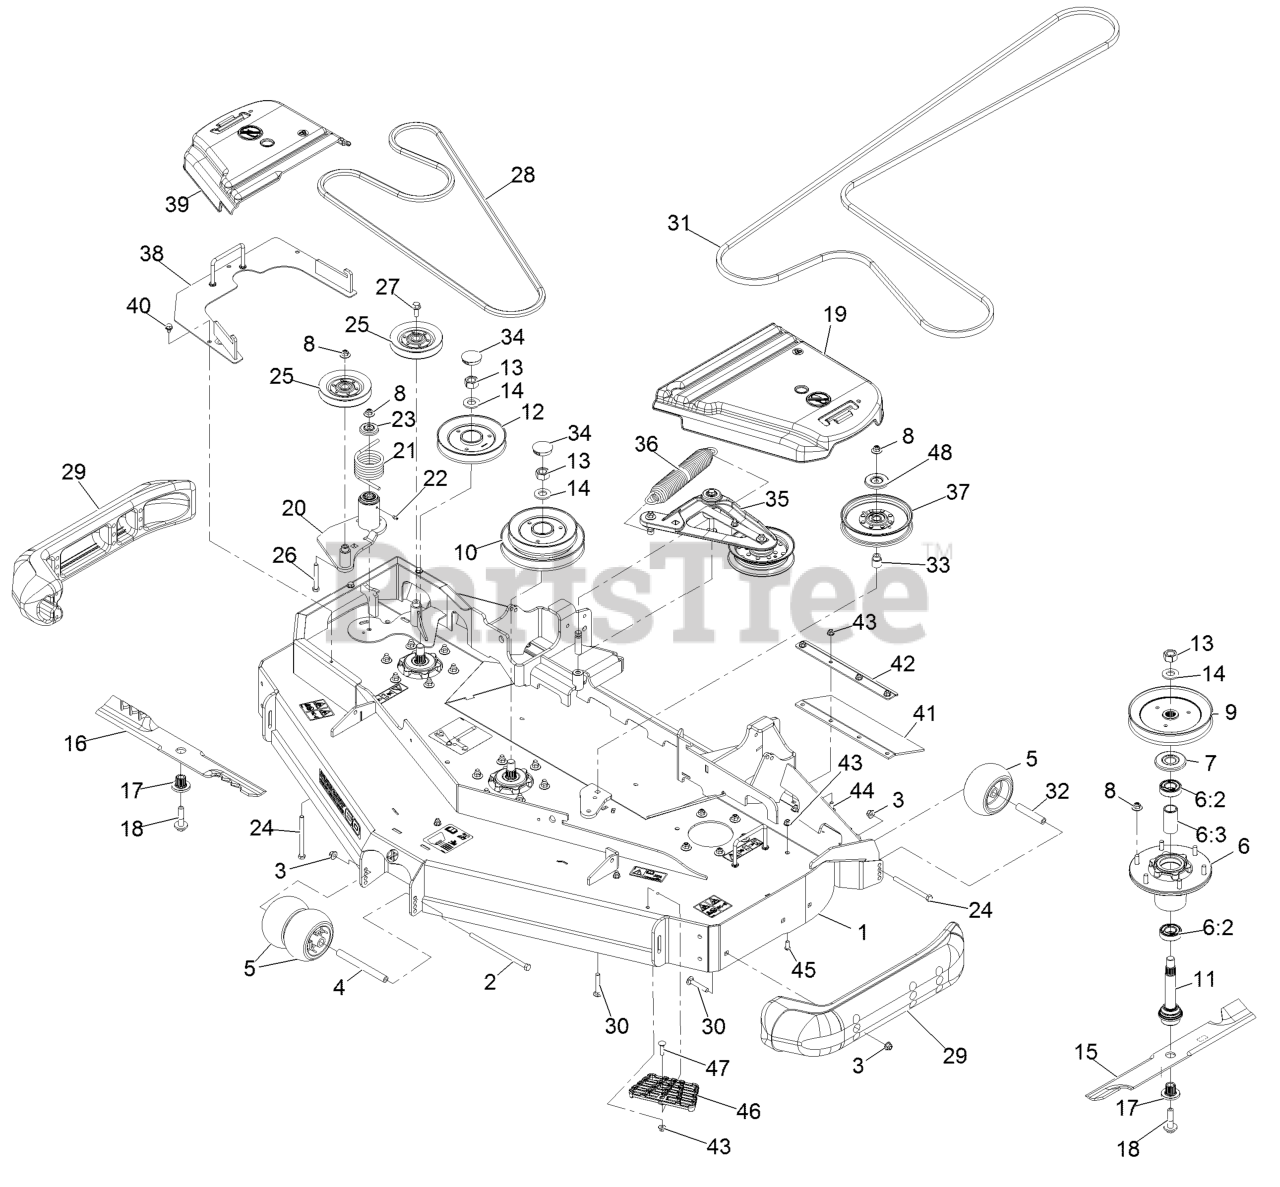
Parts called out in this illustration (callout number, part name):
1	Deck-Rd60 Nlz, W/Decals
2	Screw-HH 3/8-16 X 7 3/8
3	Nut-Nyloc 3/8-16 Flg
4	Spacer-Wheel
5	Roller-Scalp, Anti
6	ASM-Cutter Hsg With Bearings
6:2	Bearing-Ball
6:3	Spacer-Bearing
7	Guard,Bearing Top .989
8	Nut-Nyloc 3/8-16 Flg
9	Sheave,Blade Drive 7.25
10	Sheave, Double 60Rd
11	ASM-Spindle And Seal
12	Sheave-Rd Rev Drive Series 4
13	Nut-Hex
14	Washer-Spring Disc 3/4
15	Blade, Low Lift
15	Blade, Notched
15	Blade-Extreme 2, 20.50"
16	Blade-Extreme 2-20.50, Rd60
16	Blade-Low Lift 20.5, Rd60
17	Bushing, Splined
18	Screw-Sems 1/2-20 X 2.19
19	Cover-Belt, LH
20	Idler ASM
21	Spring-Torsion
22	Zerk-1/4-28 Str
23	Guard-Top
24	Screw-HH 3/8-16 X 4-1/2
26	Screw-HH 3/8-16 X 2 3/4
27	Screw-HH Flg 3/8-16 X 1
28	Belt
29	Skid-Bumper, Deck
30	Bolt-Carriage 3/8-16 X 2 1/4
31	Belt
32	Tube-Spanner
33	Bushing, Idler
34	Plug,Black Nylon 1.75
35	Deck Idler ASM
36	Spring-Extension
37	Idler-Pulley, Flat 6.00X1.00
38	Cover-Drive Reverse
39	Cover-Belt, RH
40	Screw-HWH 5/16 X 1/2 Tf
41	Guard-Tire
42	Support-Outer Flap
43	Nut-Nyloc 5/16-18 Flg
44	Bolt-Carriage 5/16-18 X 7/8
45	Screw-Button Head 5/16-18 X 3/4
46	Step-Deck
47	Screw-CARR
48	Shield-Dust
